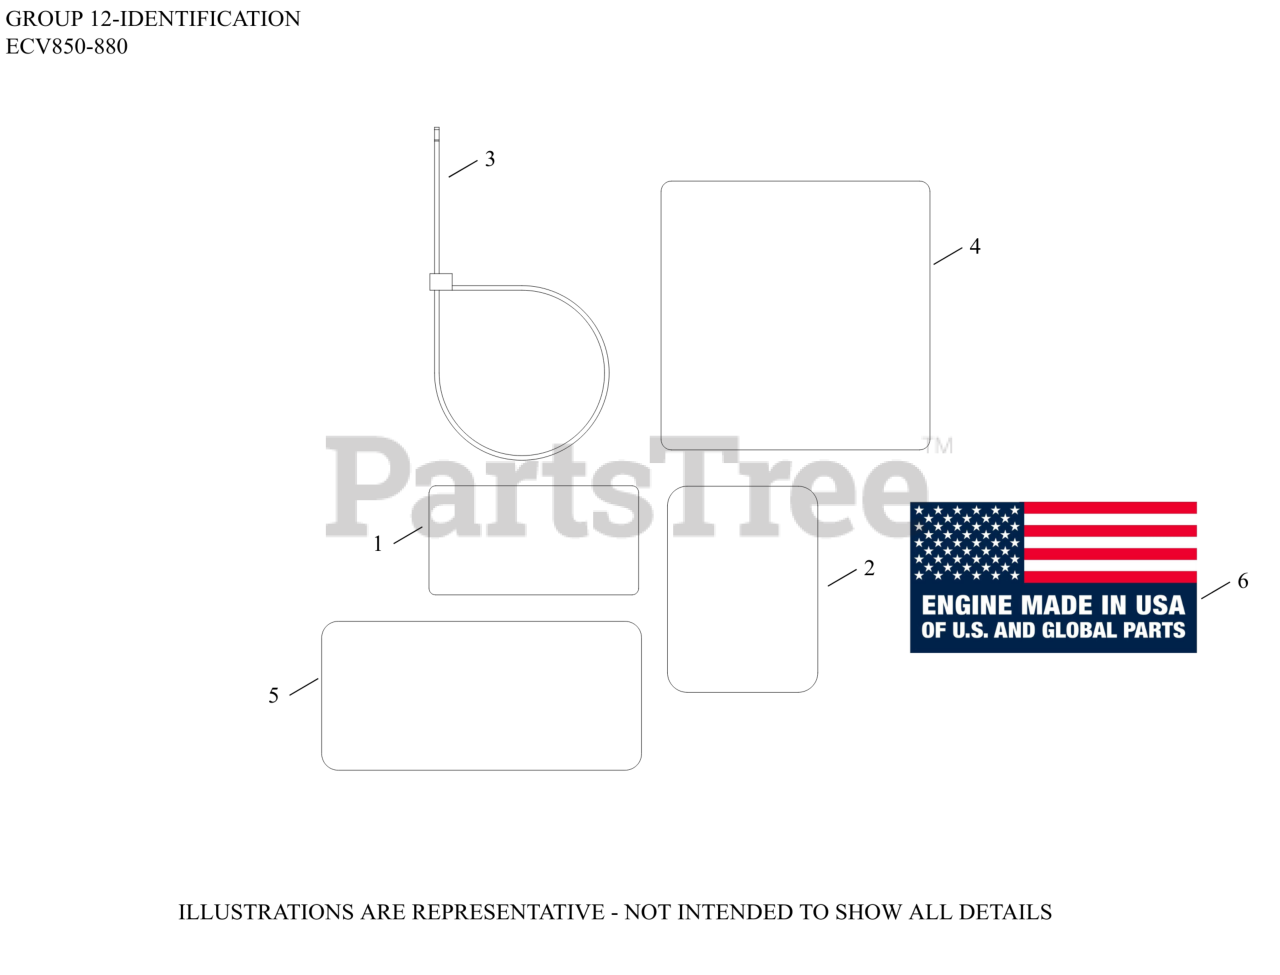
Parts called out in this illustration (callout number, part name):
1	LABEL, EFI FUEL FILTER
2	LABEL, CLEAR LAMINATION
4	DECAL, COMMAND PRO 27HP (ECV850, HDAC)
